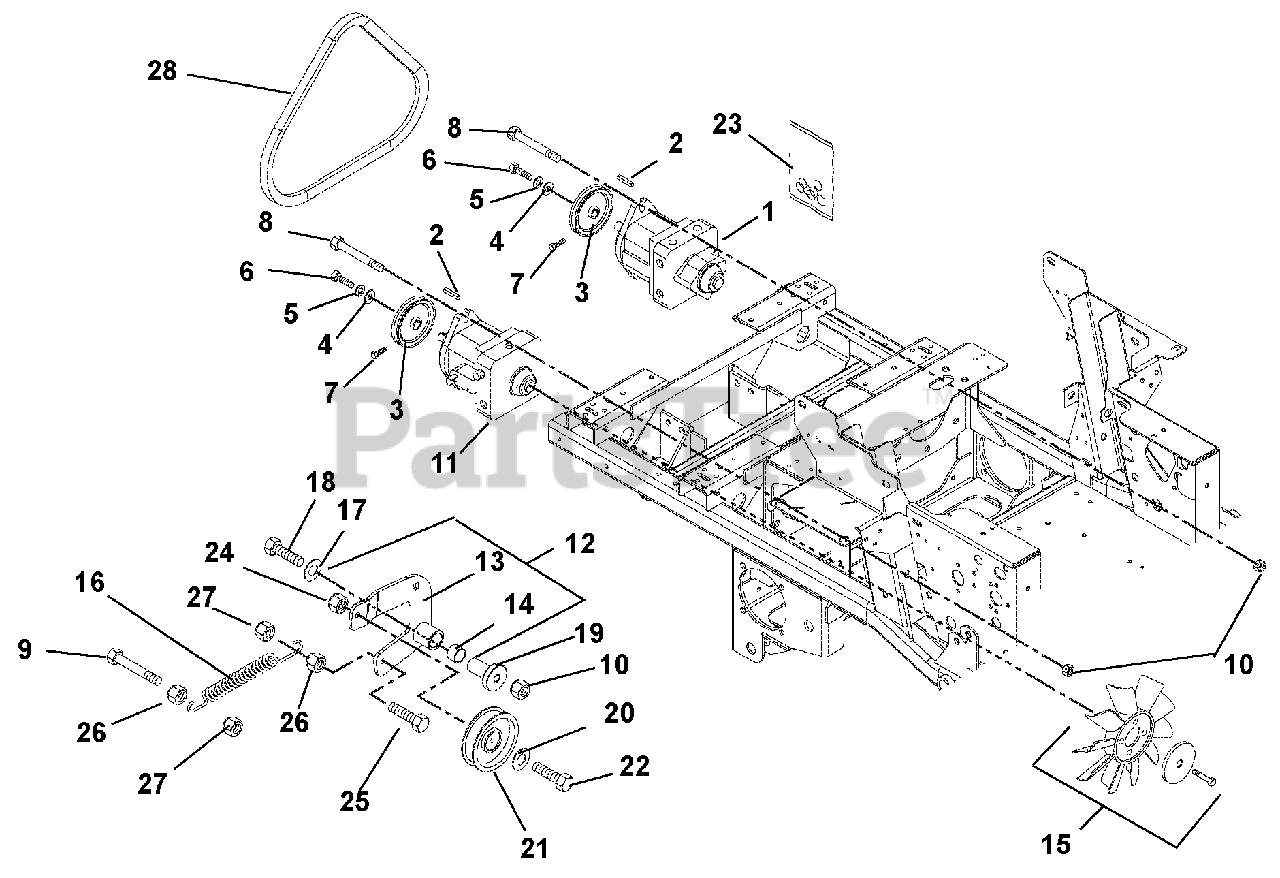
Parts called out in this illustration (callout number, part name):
1	Pump, Hydraulic (RTN) with Auxiliary
2	Key, Square 5 x 5 x 30mm Plain
3	Sheave, Poly-V .671 x 4.125
4	Washer, Flat Steel .281 x 1.000 x .063
5	Washer, Locking .25 x .062
6	Bolt, Hex M6 x 1 x 12 YZ EP30
7	Screw, Socket Head .25-20 x .50 YZ EP80
8	Bolt, Hex .50-13 x 1.50 Grade 5
9	Bolt, Hex .31-18 x 2.50 Grade 5
10	Nut, Locking Top Flange .50-13
11	Pump, Hydraulic (RTN)
12	Assembly, Idler Arm Guard Drive (Includes 13 & 14)
13	Weldment, Idler Arm Ground Drive
14	Bushing, 1.00 x 1.125 x 1.936
15	Fan, Hydro Pump Cooling
16	Spring, Tension .120 x .845 x 6.500
17	Washer, Flat Steel .39 x.75 x.125
18	Bolt, Hex .50-13 x 3.50 Grade 5
19	Bearing, Pedestal
20	Washer, Flat Steel .406 x .812 x .065
21	Assembly, Idler 4"
22	Bolt, Hex .38-16 x 2.0 Grade 5
23	Kit, Pump Seal (One kit required for each pump)
24	Nut, Locking Top Flange .38-16
25	Bolt, Hex .31-18 x 1.25 Grade 5
26	Nut, Hex .31-18
27	Nut, Locking Top Flange .31-18
28	Belt, Poly-V 49.50, Hydrostatic 200Z Series
